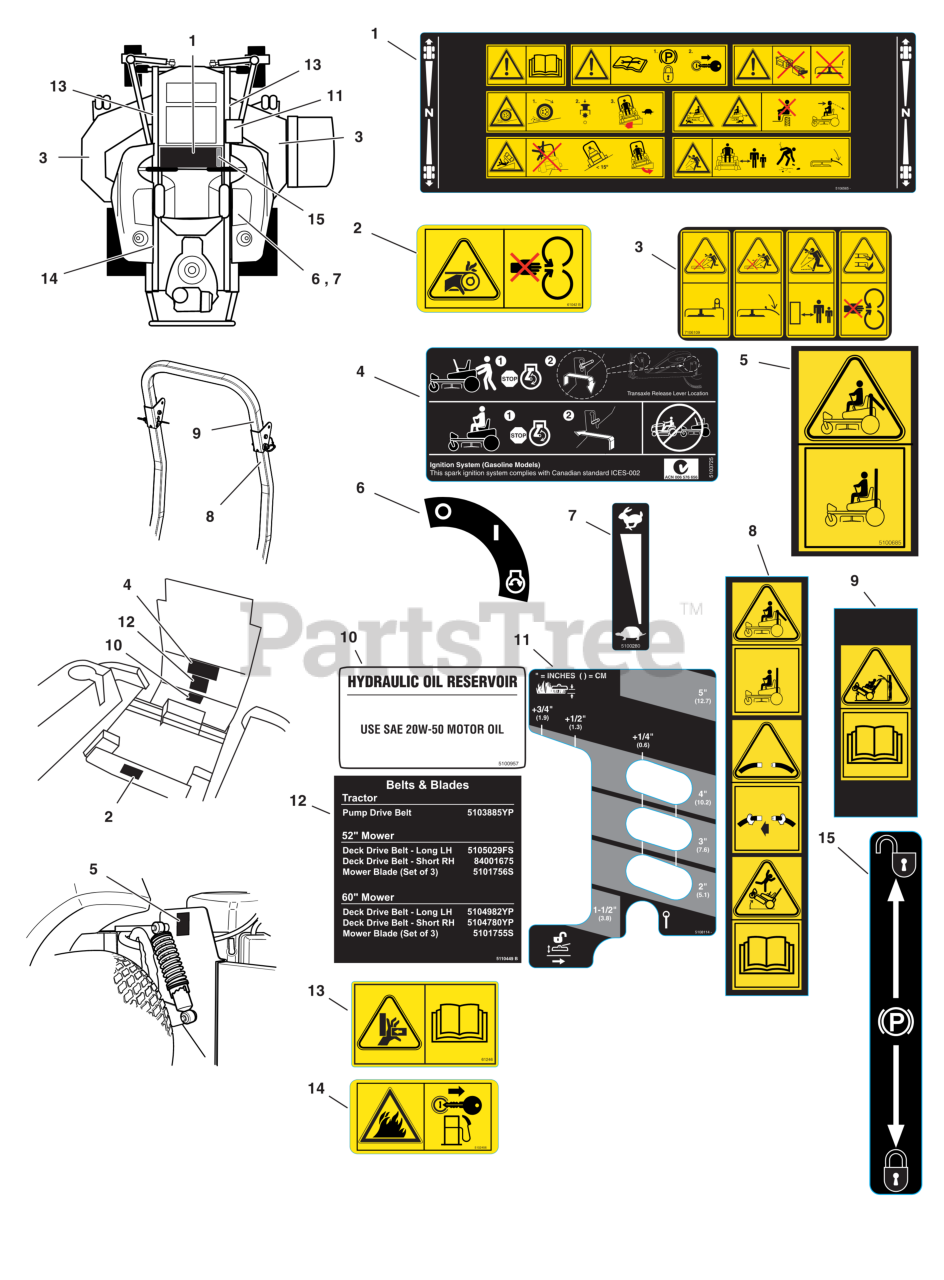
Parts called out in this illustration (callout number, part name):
1	DECAL, Warning/Safety
2	DECAL, CE DANGER
3	DECAL, DISCHARGE
4	DECAL, TRANS RELEASE
5	DECAL, WARNING, ROLL
6	DECAL, IGNITION SWITC
7	DECAL, THROTTLE CONTR
8	DECAL, SAFETY, ROPS
9	DECAL, SAFETY, ROPS
11	DECAL, CUTTING HEIGHT
12	DECAL, Belt & Blade
13	DECAL, PINCH POINT
14	DECAL, FIRE ANSI EXPO
15	DECAL, PARKING BRAKE
